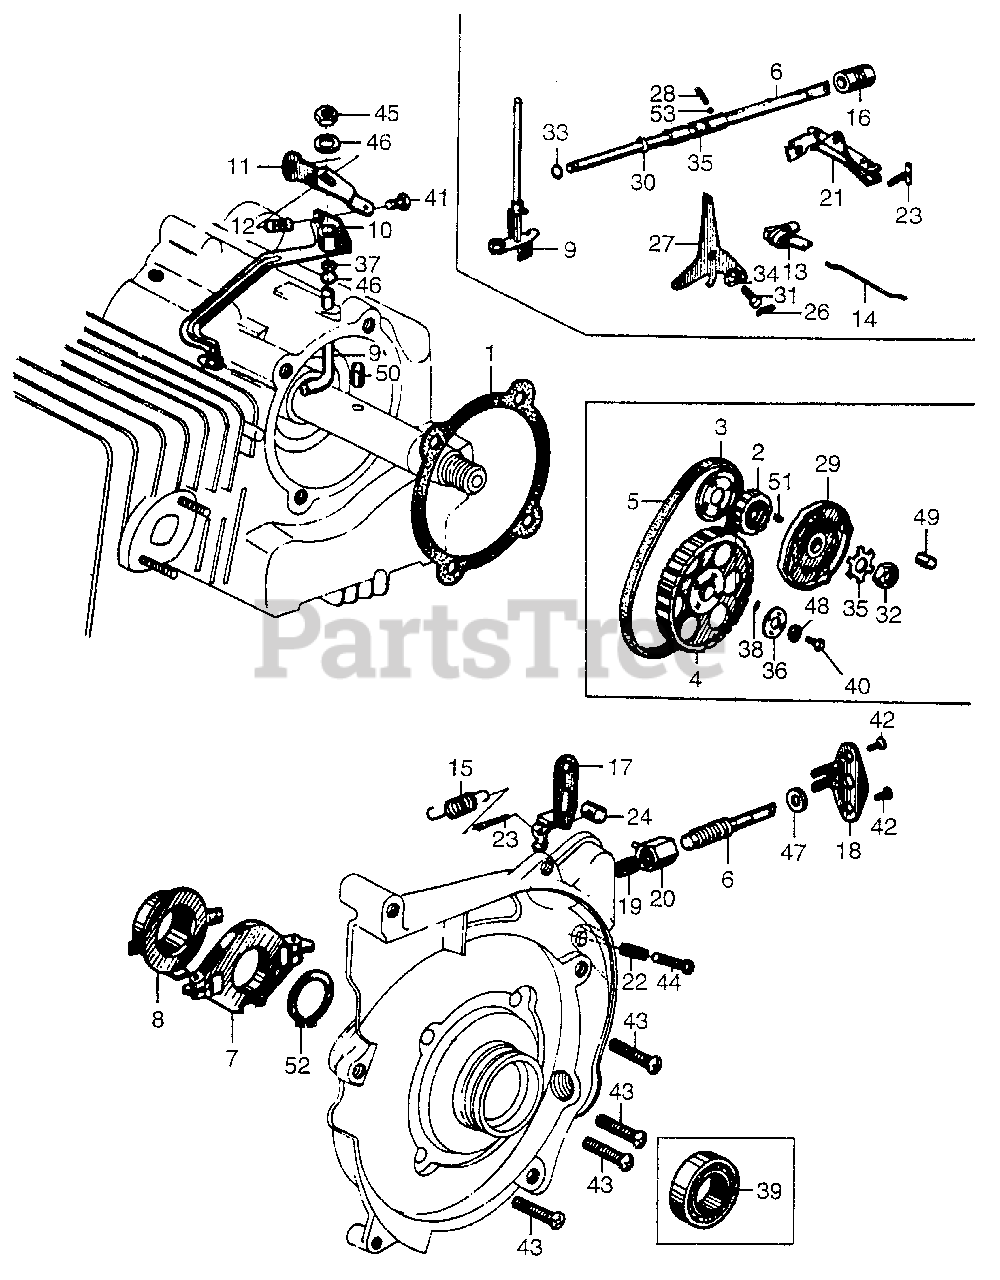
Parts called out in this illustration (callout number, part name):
1	GASKET, STARTER CASE (NOT AVAILABLE)
6	SHAFT, CONTROL ADJUST
7	HOLDER, GOVERNOR WEIGHT
8	SLIDER, GOVERNOR
9	SHAFT, GOVERNOR ARM
10	ARM, GOVERNOR (NOT AVAILABLE)
11	PLATE, GOVERNOR ADJUST
12	SPRING, GOVERNOR ARM ADJUST
15	SPRING, GOVERNOR
17	ARM, CONTROL
18	RETAINER, ADJUST SHAFT
19	SPRING, ADJUST SHAFT
20	NUT, CONTROL ADJUSTING (NOT AVAILABLE)
22	SPRING, CONTROL ADJUSTING
23	BOLT, SPRING ADJUST
24	NUT, SPRING ADJUST
37	WASHER, PLAIN (5MM)
41	BOLT, RECESSED (4X18)
42	SCREW, PAN (4X6)
43	SCREW, PAN (5X22)
44	SCREW, PAN (4X20)
45	NUT, HEX. (4MM)
46	E-RING (4MM)
47	WASHER, PLAIN (6MM)
52	CIRCLIP (OUTER) (15MM)
